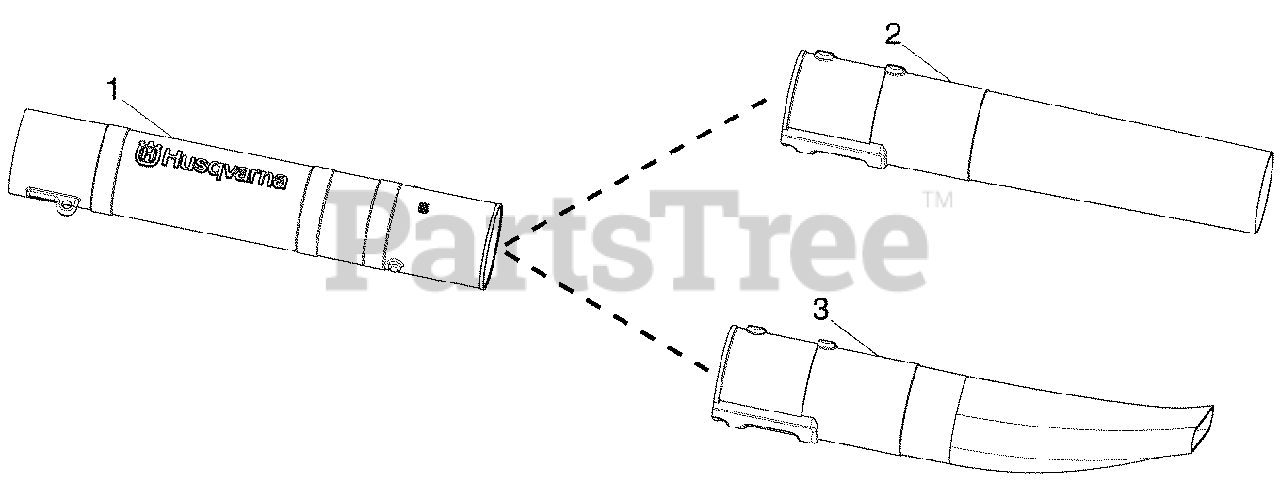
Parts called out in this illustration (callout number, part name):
1	Assy - Tube - Upper Blower w/barrier
2	Tube - Lower Blower
3	Tube - Lower Blower Flare
